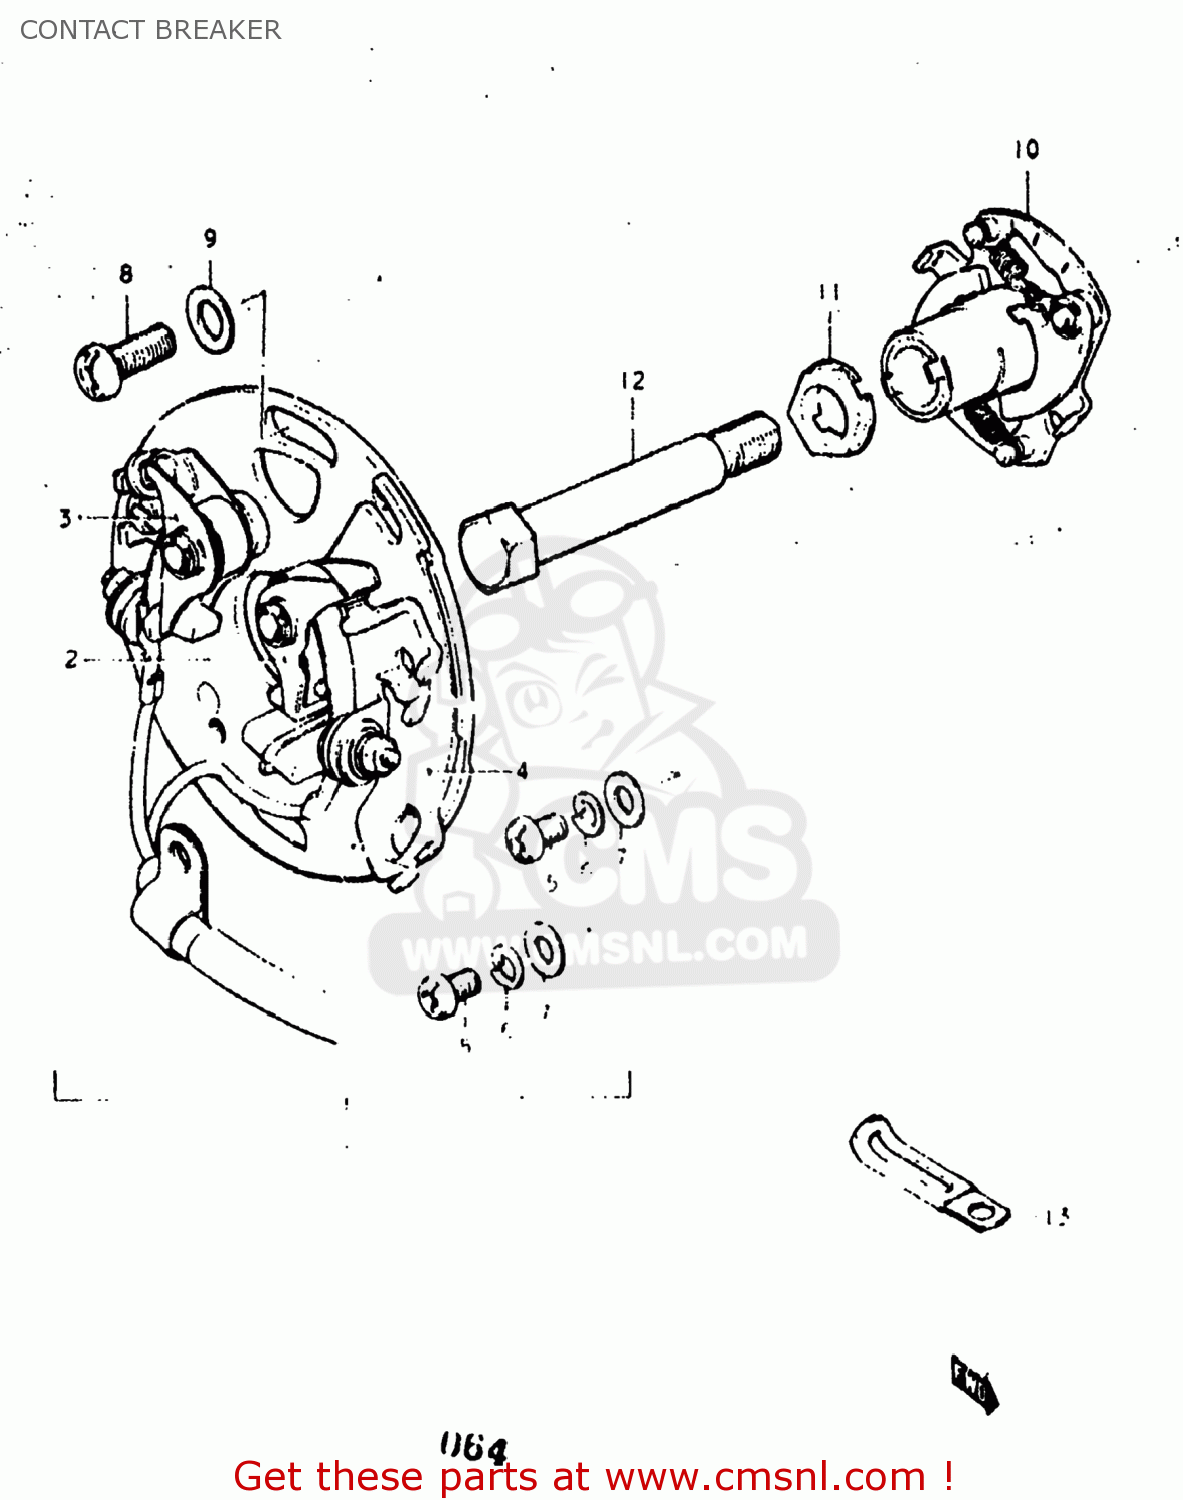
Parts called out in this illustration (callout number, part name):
1	BREAKER ASSY,CONTACT
2	POINT ASSEMBLY,CONTACT,RIGHT
3	POINT ASSEMBLY,CONTACT,LEFT
4	PLATE,CONTACT POINT
5	SCREW(4X10)
6	LOCK WASHER
7	WASHER
8	SCREW(5X12)
9	WASHER 5MM
10	GOVERNOR ASSEMBLY
11	WASHER
12	BOLT
13	CLAMP L:35
